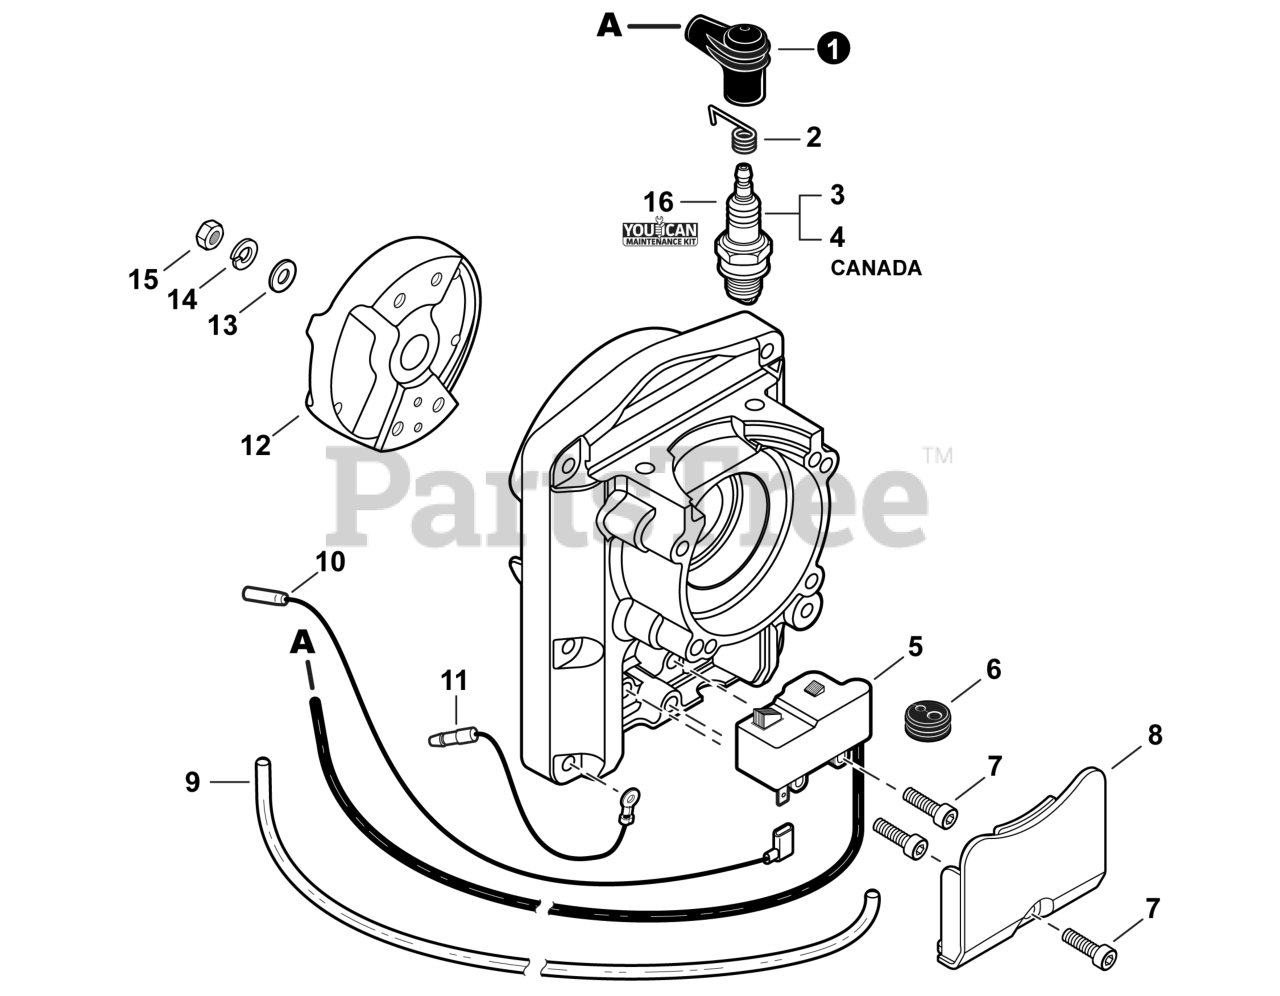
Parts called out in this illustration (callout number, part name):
1	CAP, SPARK PLUG
2	TERMINAL, SPARK PLUG
3	SPARK PLUG - BPM8Y
4	SPARK PLUG - BPMR8Y
5	COIL, IGNITION
7	BOLT, TORX 5x16
8	COVER, DUST
10	LEAD - IGNITION
11	LEAD - GROUND
12	FLYWHEEL
13	WASHER M10
16	TUNE-UP KIT - YOUCANT
